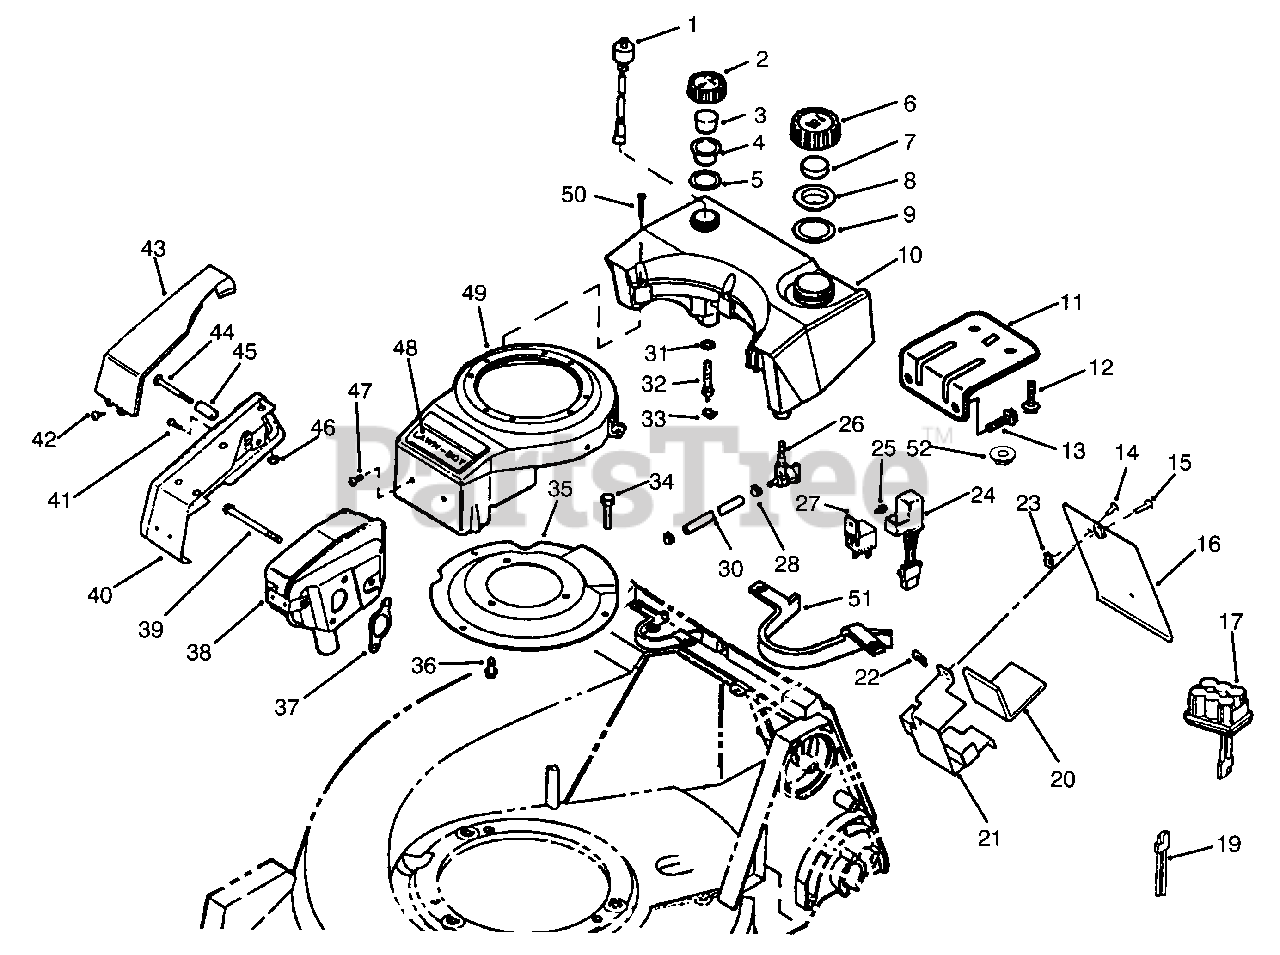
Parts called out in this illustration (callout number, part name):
1	Switch-Low Oil
2	Assembly-Cap, Oil (Incl. Ref. #3-5)
6	Assembly-Cap, Fuel (Incl. Ref. #7-9)
10	Assy-Fuel/Oil Tank (Incl. Ref. #1, 26 & 31-32)
11	Bracket-Tank, Fuel/Oil
12	Screw-Mounting, Tank
13	Bolt-Bracket/Starter
14	Screw-Bracket to Door
16	Door-Access
17	Pack-Battery (Incl. Ref. #18)
19	Harness-Wire, Lower
20	Pad-Battery
21	Bracket-Battery
22	Speednut
23	Speednut
24	Assembly-Cup, Electronic
25	Screw
26	Valve-Fuel, Shut-Off
27	Relay-Starter
28	Clamp-Fuel Line
30	Fuel Line
32	Assembly-Fitting, Oil
33	Clamp-Hose, Oil
35	Plate-Engine, Mounting
37	Gasket-Exhaust
38	Muffler
39	Screw-Muffler
40	Assembly-Guard, Muffler (Incl. Ref. #43 & 46)
41	Screw-Guard, Muffler
42	Screw-Guard, Muffler
43	Cover-Muffler
44	Screw-Guard, Muffler
45	Spacer-Guard, Muffler
46	Pushnut
47	Screw-Shroud
48	Applique
49	Assy.-Shroud & Applique (Incl. Ref. #48)
50	Screw-Tank, Fuel
51	Snubber-Belt
